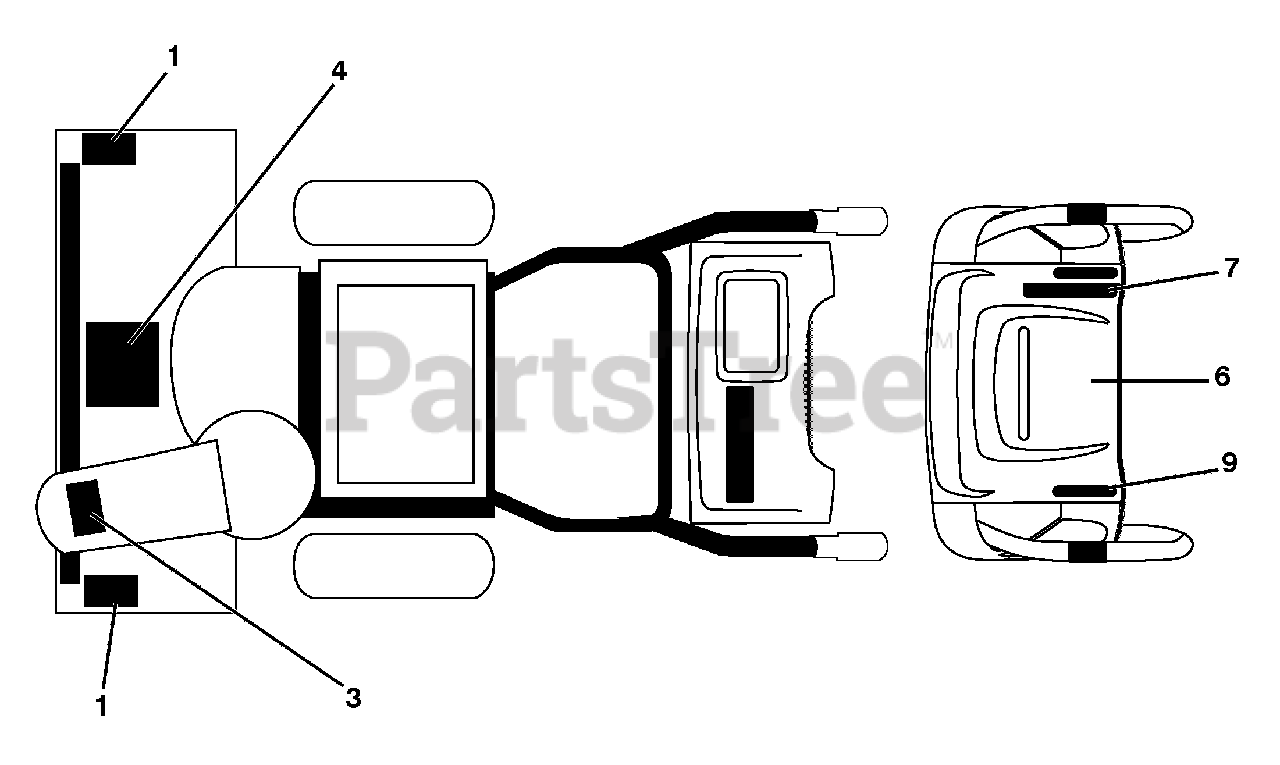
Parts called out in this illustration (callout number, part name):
1	DECAL, DANGER
3	DECAL, DANGER, DEFLECTOR
4	DECAL, AUGER READ OWN MAN E/F
6	DECAL, CONS CENTER INST E/F GY
7	DECAL, CONS RT SPD/LEV/PWRST GY
9	DECAL, CONS LT SPD/LEV/PWRST GY
